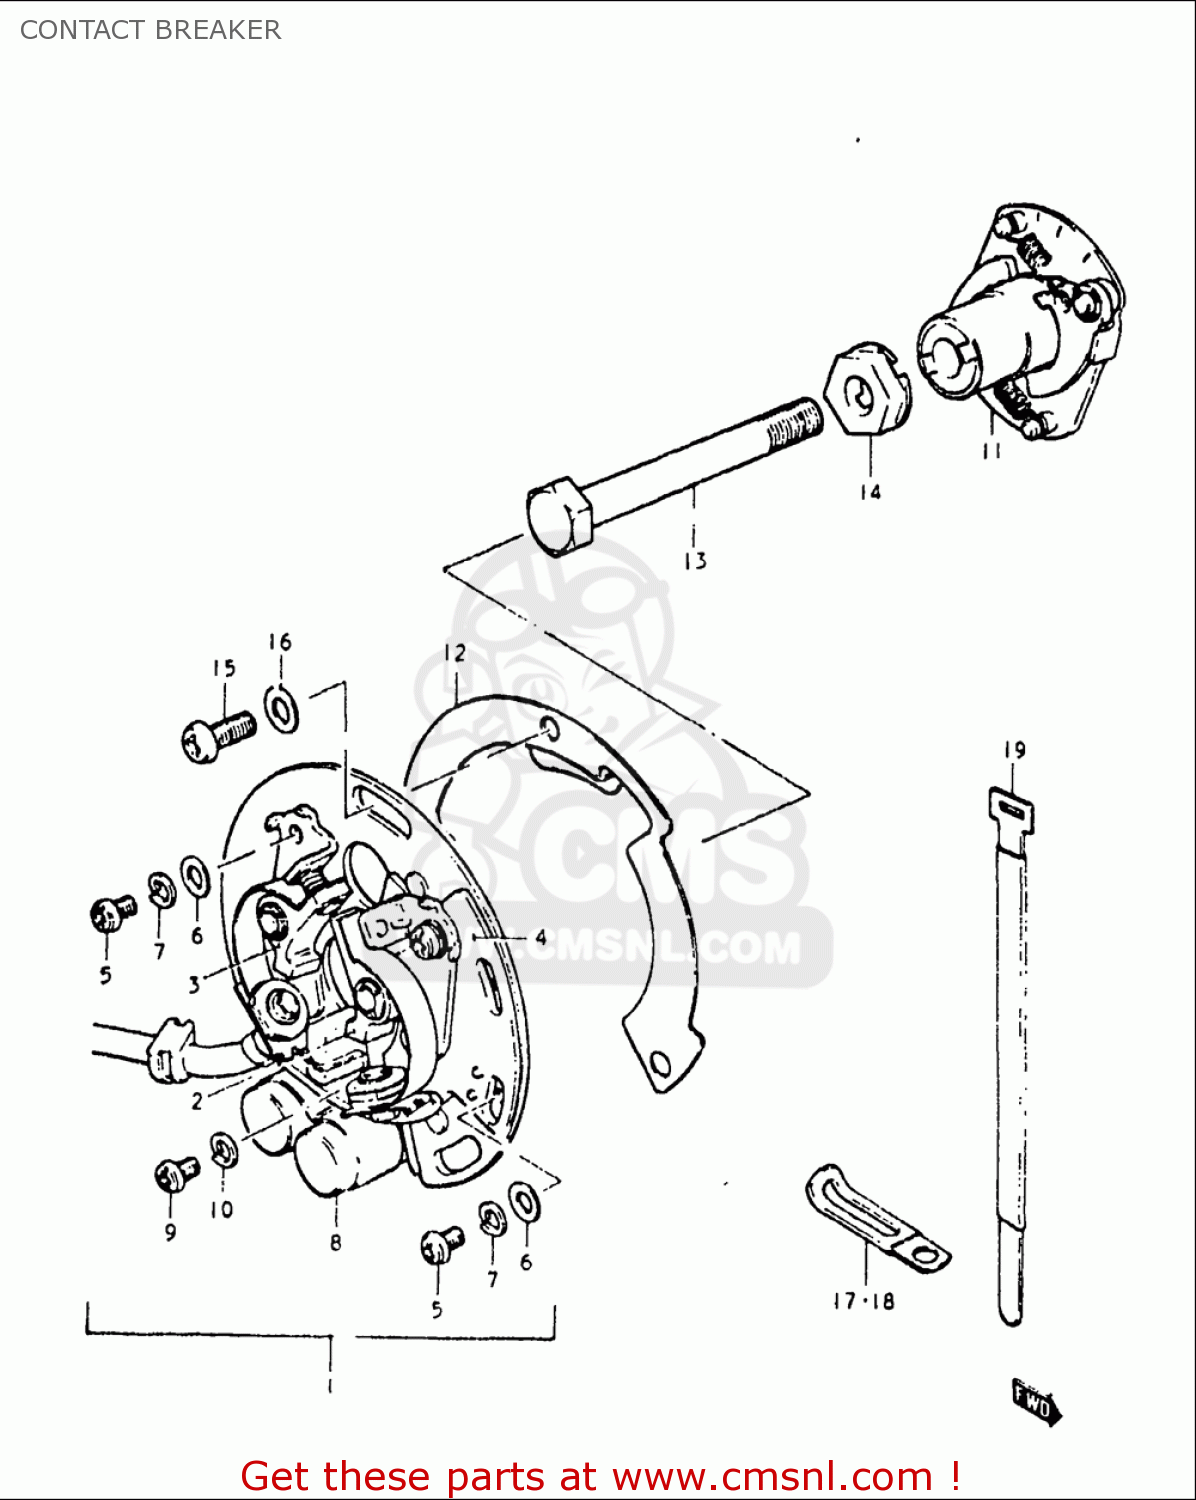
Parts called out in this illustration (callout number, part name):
1	BREAKER ASSY
2	POINT ASSY,CONTACT,R
3	POINT ASSY,CONTACT,L
4	PLATE,CONTACT POINT
5	SCREW 4X6
6	WASHER
7	WASHER,LOCK
8	CONDENSER
9	SCREW 4X6
10	WASHER,LOCK
11	GOVERNOR ASSEMBLY
12	PLATE,IGNITION TIMING
13	BOLT
14	WASHER
15	SCREW(5X12)
16	WASHER
17	CLAMP(L:65)
18	CLAMP(L:120 T:1.0)
19	CLAMP
